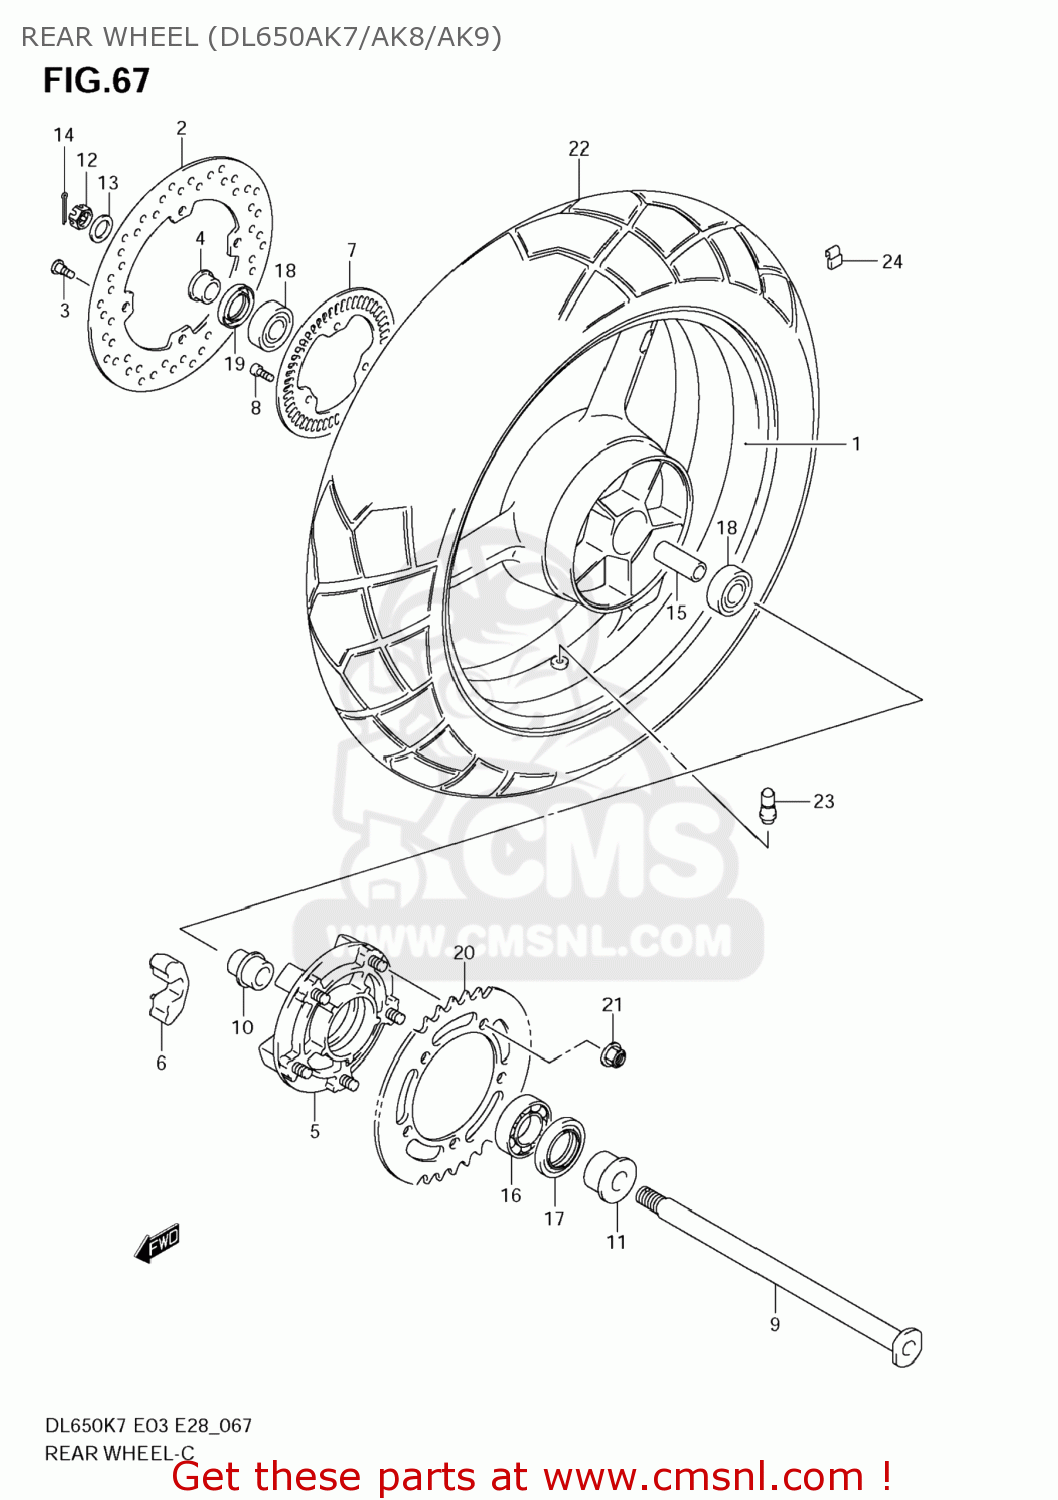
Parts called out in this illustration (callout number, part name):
1	WHEEL,RR(17M/CXMT4.00)
2	DISC,RR BRAKE
3	BOLT(8X21)
4	SPACER,RR AXLE,R
5	DRUM, REAR SPROCKET
6	ABSORBER,RR HUB SHOCK
7	RING,SPEED SENSOR FR(50T)
8	BOLT
9	AXLE,RR
10	RETAINER,RR SPROCKET DRUM
11	SPACER,RR AXLE,L
12	NUT
13	WASHER(18.5X28X2.6)
14	PIN
15	SPACER(20.8X27.2X124)
16	BEARING
17	SEAL,OIL(39X65X7)
18	BEARING
19	SEAL,OIL(28X47X7)
20	SPROCKET,RR(47T-525)
21	NUT
22	TIRE,REAR,150/
23	VALVE ASSY,WHEEL RIM(TR412)
24	WEIGHT,WHEEL BALANCE 10G
